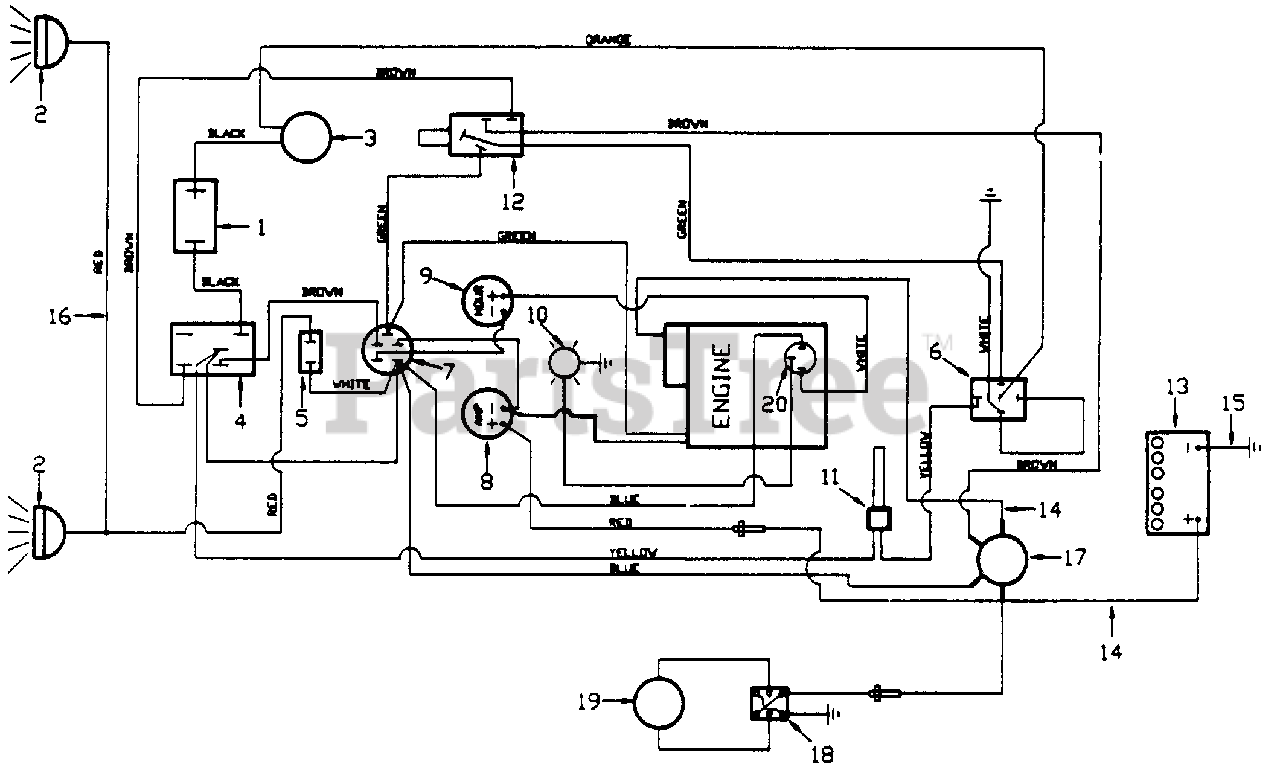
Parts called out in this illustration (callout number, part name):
1	10 Amp Circut Breaker
2	Headlight Assembly
3	Elecerlc Clutch Assembly
4	PT0 Clutch Swltch
5	Light Swltch
6	Relay
7	Ignitlon Switch
13	Battery
16	Light to Switch Wire
18	3 Position Deck Lift Switch
19	Electrlc Lift Actuator
20	Oil Sending Unit
